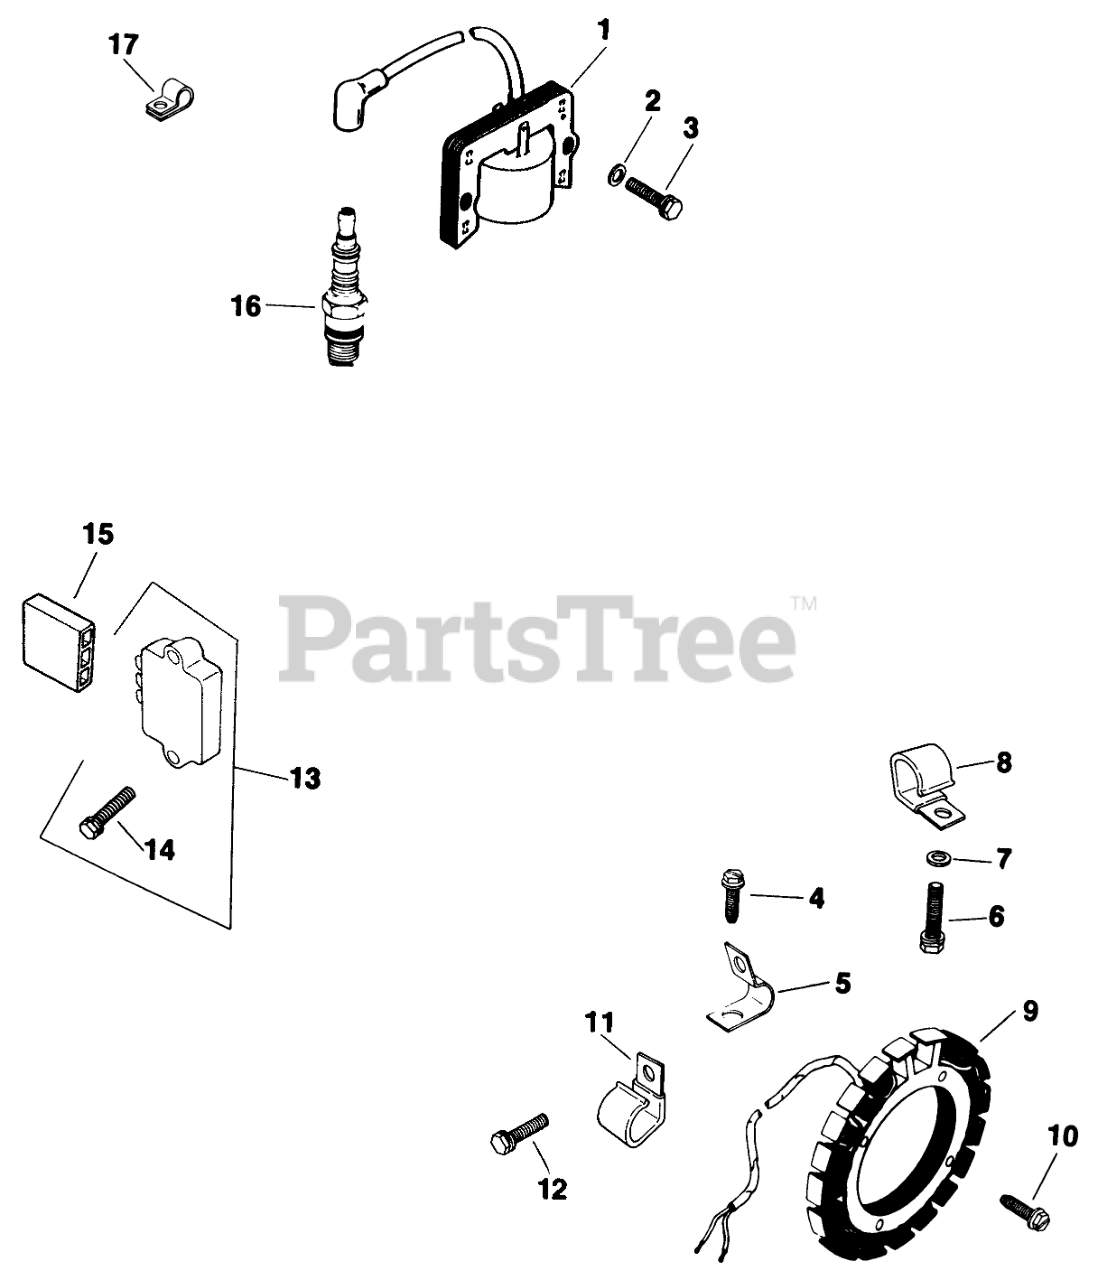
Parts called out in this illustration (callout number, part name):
1	Module-Ignition
2	Washer
3	Screw
4	Screw-Hex. Hd.
8	Clip
9	Stator Kit 15 amp (Includes Item #8)
10	Screw
11	Clip
13	Regulator-Rectifier
14	Screw
15	Connector
16	Plug-Spark
17	Clip-Hi-Tension
